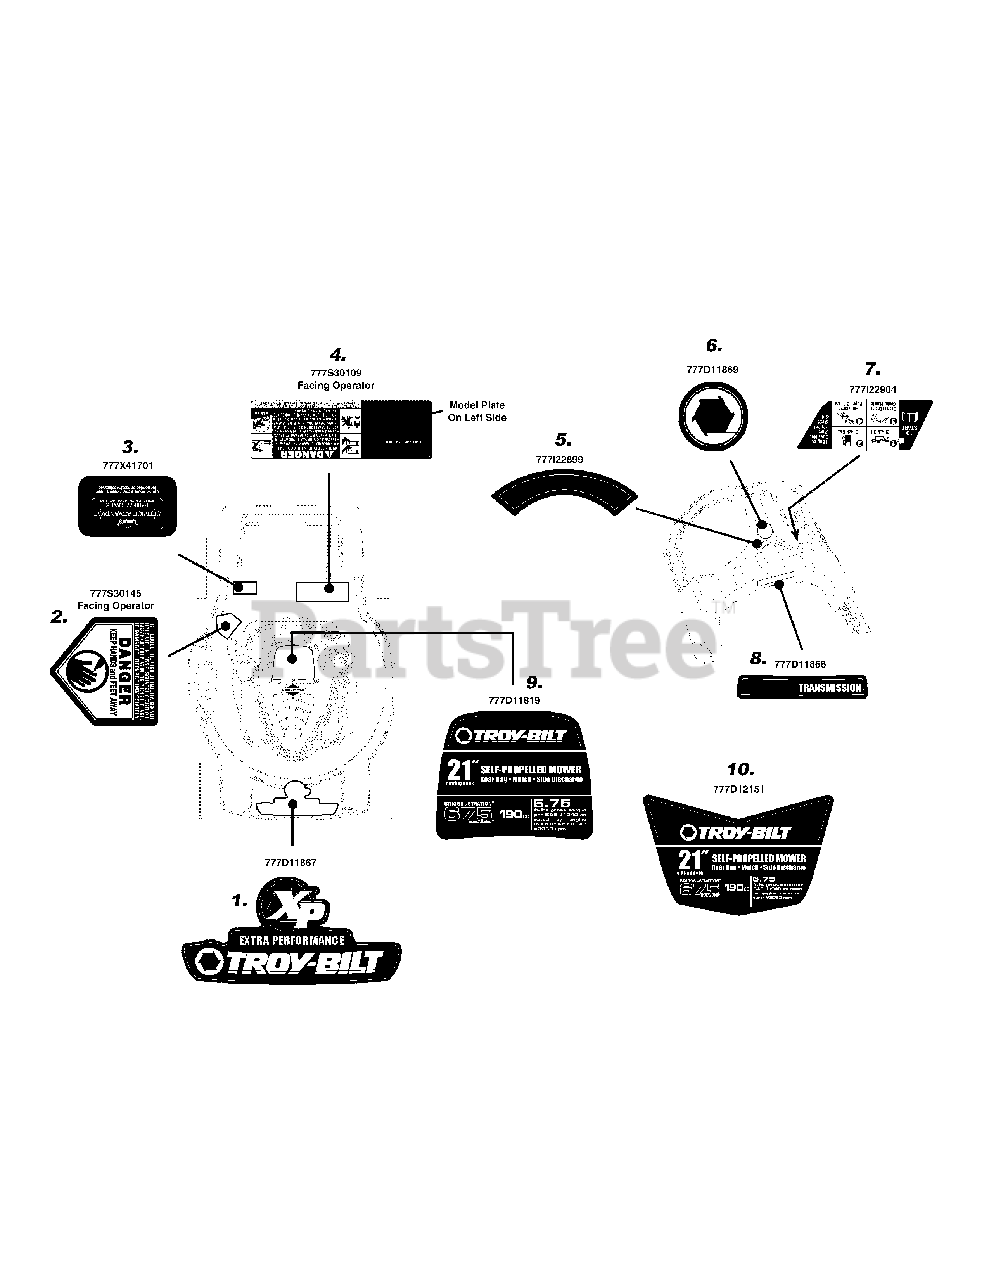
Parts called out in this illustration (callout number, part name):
1	LABEL-MOWER 800 XP TROY
2	LABEL
3	LBL:LOWES SERVICE ADVANTAGE
4	LBL:MWR:DNGR:STRGHT:W/O 1-800
5	LABEL-MOWER XP HANDLE SELECT
6	LABEL-EMBOSSED TROYBILT
7	LABEL-MOWER HANDLE B&S
8	LABEL-MOWER XP HANDLE SELECT TROY
9	LABEL-MOWER SHROUD TROY 675
10	LABEL-MOWER SHROUD TROY
